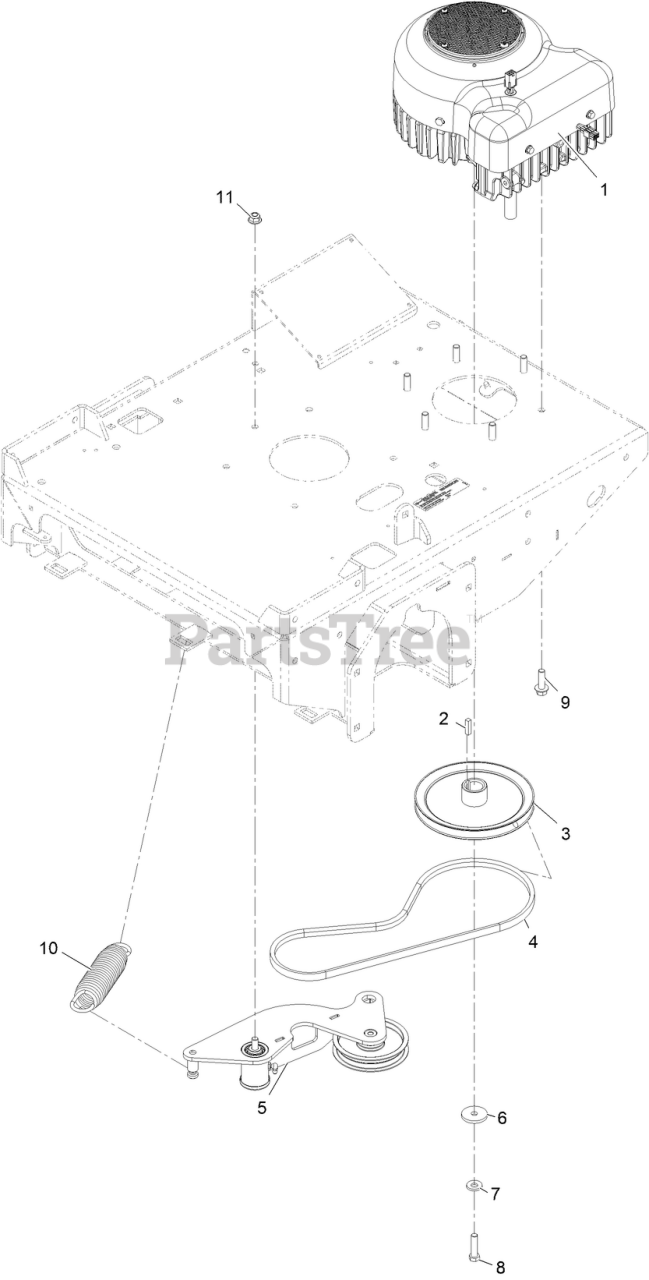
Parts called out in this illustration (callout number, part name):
1	Generator/Controller ASM
3	SHEAVE-GENERATOR
5	IDLER ARM ASM
6	Washer-Plain
7	WASHER-BELLEVILLE
8	SCREW-HH
9	SCREW-HHF
10	SPRING-EXTENSION
11	NUT-HF, NI
